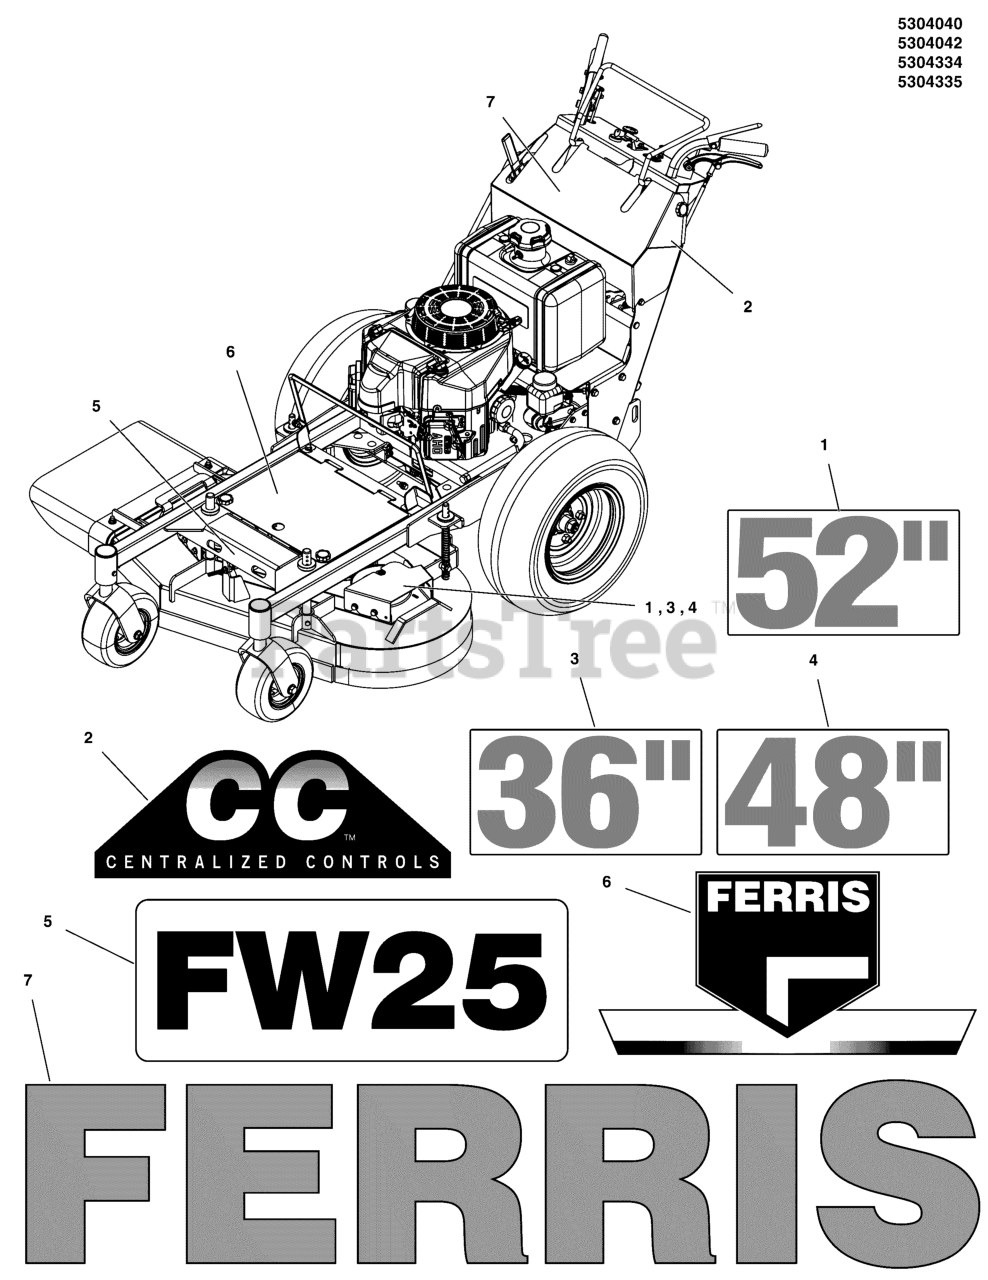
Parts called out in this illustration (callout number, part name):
1	DECAL, 52
2	DECAL, CENTRALIZED CONTROLS
3	DECAL, 36
4	DECAL, 48
5	DECAL, MODEL SERIES, FW25
6	DECAL, FERRIS, FRONT, 8.78 X 5.81
7	DECAL, FERRIS, 2.23" X 11.39"
